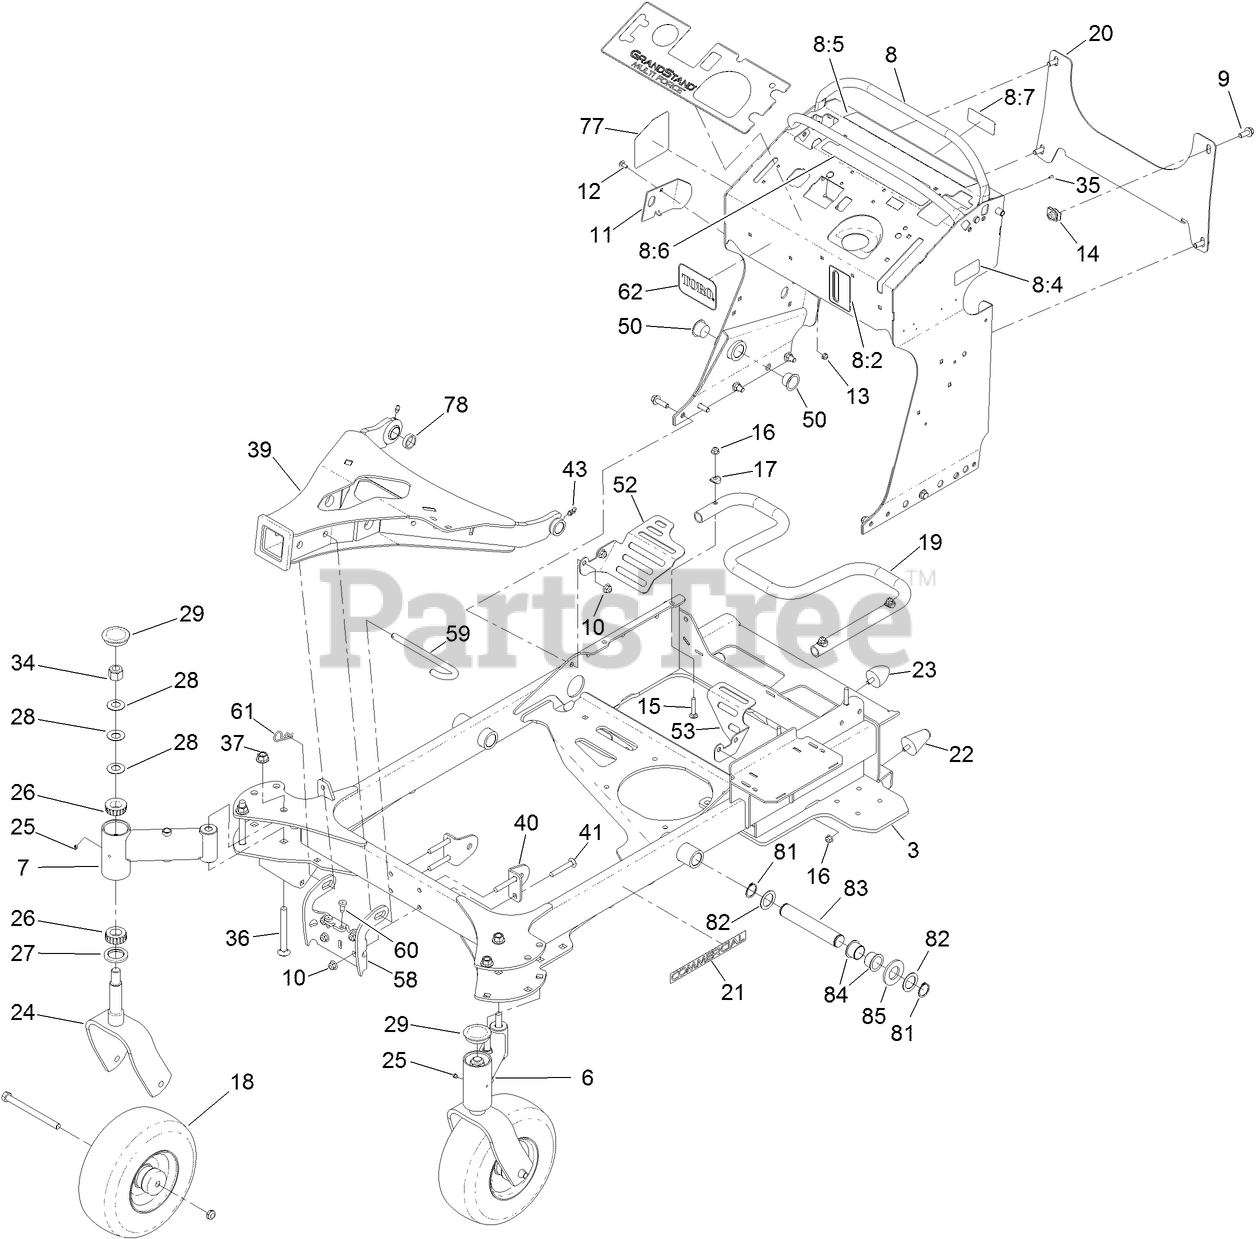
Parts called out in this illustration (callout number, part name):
6	TUBE CASTOR SHORT
7	TUBE CASTOR LONG
8	TOWER DECAL ASM
8:2	DECAL-LEVEL, OIL
8:4	DECAL-FILL, FUEL
8:5	DECAL-CAUTION
8:6	DECAL-CONTROLS
8:7	DECAL-FUSE
9	SCREW-HHF
10	NUT-HF, NI
11	PLATE-STRIKER
12	SCREW-CARR
13	NUT-HF
14	Nut-Tinnerman
15	BOLT-CAR
16	NUT-HF, NI
17	WASHER
18	WHEEL/TIRE AND BEARING ASM
19	TUBE-MOUNT, FUEL TANK
20	BRACKET-CROSS
21	DECAL-COMMERCIAL
22	BUMPER-RUBBER
23	BUMPER-RUBBER
24	FORK-CASTER
26	BEARING-ROLLER, TAPERED
27	SEAL-GREASE
28	WASHER-BELLVILLE
29	CAP-GREASE
34	NUT-LOCK, NI
35	RIVET-POP
36	SCREW-CARR
37	NUT-LOCK
40	BRACKET-CYLINDER
41	SCREW-CARR
43	FITTING-GREASE, 90 DEG
50	PLUG-PLASTIC
52	GUARD-FAN, RH
53	GUARD-FAN, LH
58	BRACKET-LOCK
59	PIN-HITCH
60	BUMPER-RUBBER
61	PIN-HAIR
62	DECAL-LOGO, TORO
77	DECAL SERVICE-MULTIFORCE
78	SPACER
81	RING-RETAINING
82	WASHER-THRUST
83	SHAFT-PIVOT
84	BUSHING
85	WASHER-FLAT
